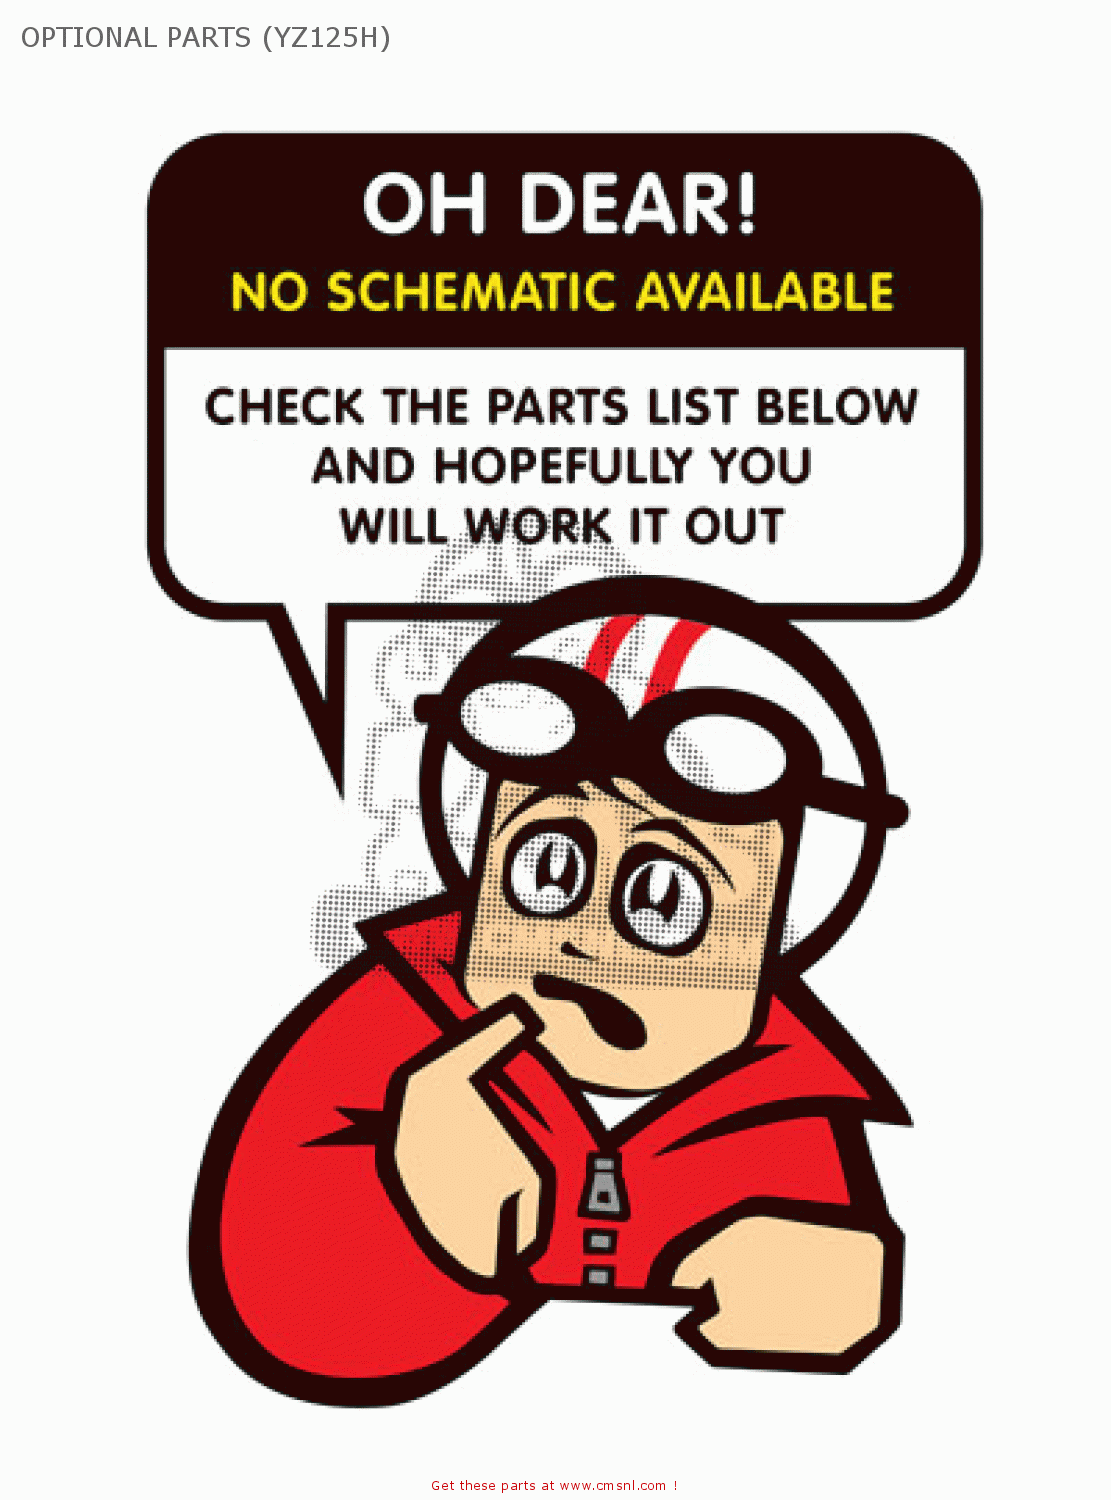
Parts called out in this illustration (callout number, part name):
1	GASKET,CYLINDER (NAS)
2	SEAL,VLV STEM
3	GSKT.CYLN.HEAD (NAS)
4	GSKT,HEAD,COVER (NAS)
5	GSKT,CYLN.HEAD R (NAS)
6	GSKT,HEAD,COVER (NAS)
7	GASKET,CARBURETOR
8	GASKET,EX.PIPE (NAS)
9	O-RING 14.5MM
10	O-RING,27X2.0
11	O RING, 30.8M/M
12	PACKING,RUB.16M/M
13	GASKET,RUBBER 9MM
14	GASKET KIT A (NAS)
